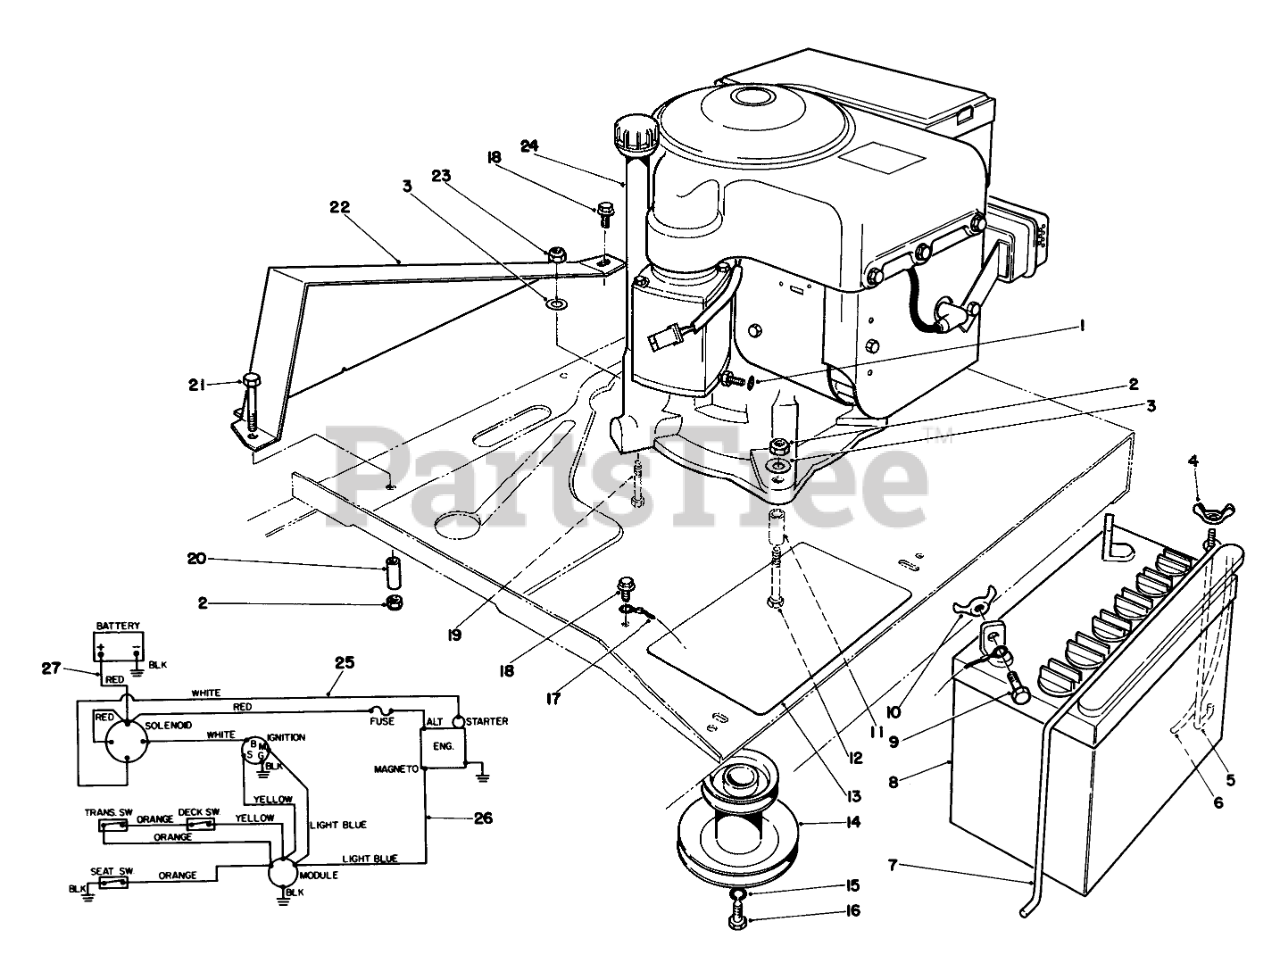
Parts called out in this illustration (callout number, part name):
1	WASHER-LOCK
2	NUT-LOCK, NI
3	WASHER-PLAIN
4	NUT-WING SPECL
5	POST-BATTERY
6	TUBE-BATT DRAIN/80-2600
7	BATTERY HOLDOWN
8	Battery
9	SCREW-HH
10	NUT-WING
11	PIVOT SPACER
12	SCREW-HH
13	PAD-SKID, ANTI
14	Pulley-Engine
15	WASHER-LOCK
16	SCREW-HH
17	ENG-GROUND WIRE ASM
18	SCREW-HWHTF
19	SCREW-HH
20	GUIDE-BELT
21	SCREW-HH
22	Guard Chain
23	NUT-LOCK, CONE
24	Engine Assy.
25	WIRE ASSEMBLY
26	WIRE HARNESS
27	WIRE ASM - BATT TO SOL
